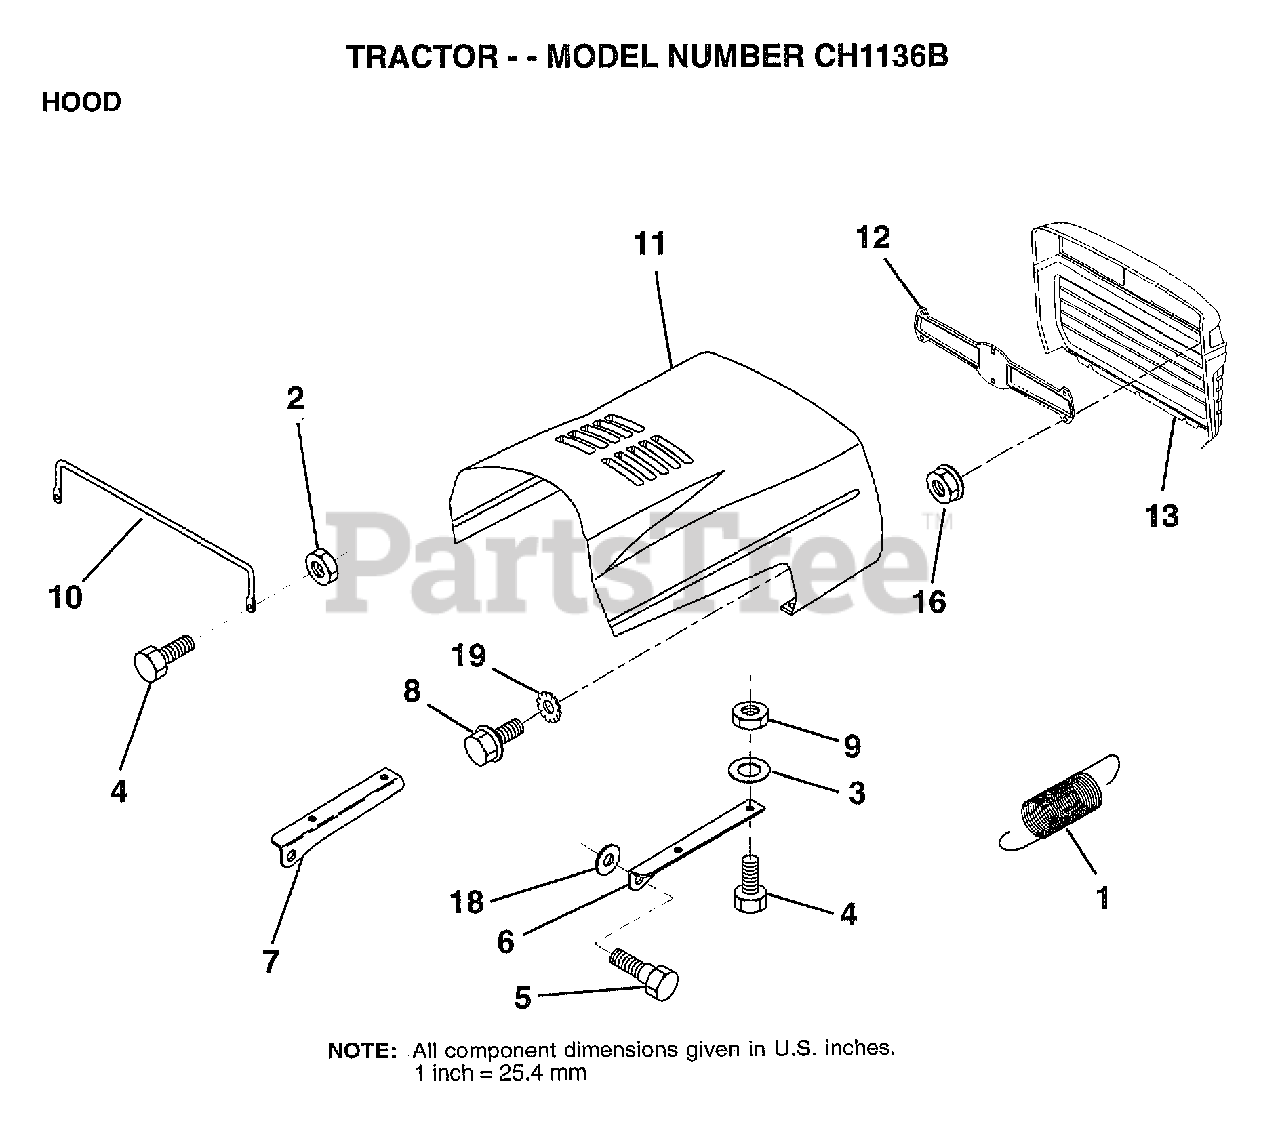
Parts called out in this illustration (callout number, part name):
1	EXT SPRING
2	NUT HXKEP 1/4X20
3	WASHER
5	BOLT.SHLD.5/16-18
6	BRKT HOOD RH
7	BRKT HOOD LH
8	SCREW SLTD HXHD
9	NUT
10	"BRACE,HOOD"
13	GRILL (BLACK)
16	NUT
18	WASHER
19	LOCKWASHER GT
